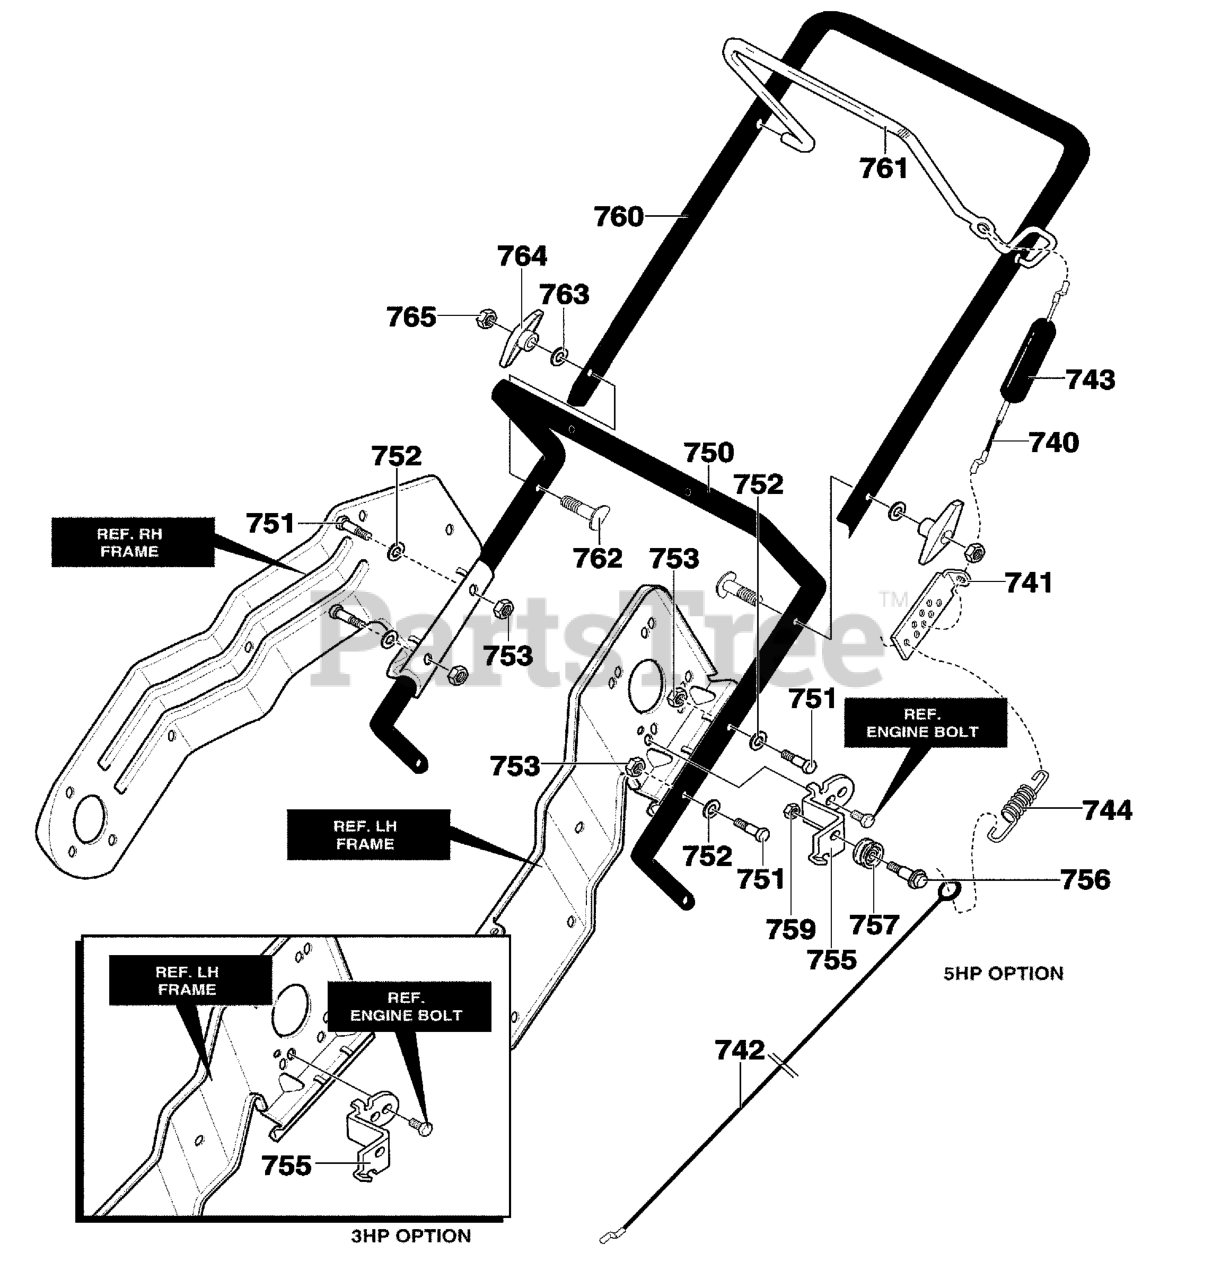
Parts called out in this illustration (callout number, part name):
740	CABLE, UPPER
741	BRACKET, CABLE ADJ
742	CABLE, LOWER CONTROL
743	BOOT, CLUTCH SPRING
744	SPRING, EXTENSION
750	HANDLE, LOWER
751	SCREW, 1/4-20X1.25
752	WASHER, FLAT
753	NUT, 1/4-20
755	BRACKET, CABLE
757	PULLEY
759	NUT, 1/4-20
760	UPPER HANDLE
761	BAIL, CONTROL
763	WASHER, FORM
764	KNOB, T 3.00 WD
765	NUT, 5/16-18
